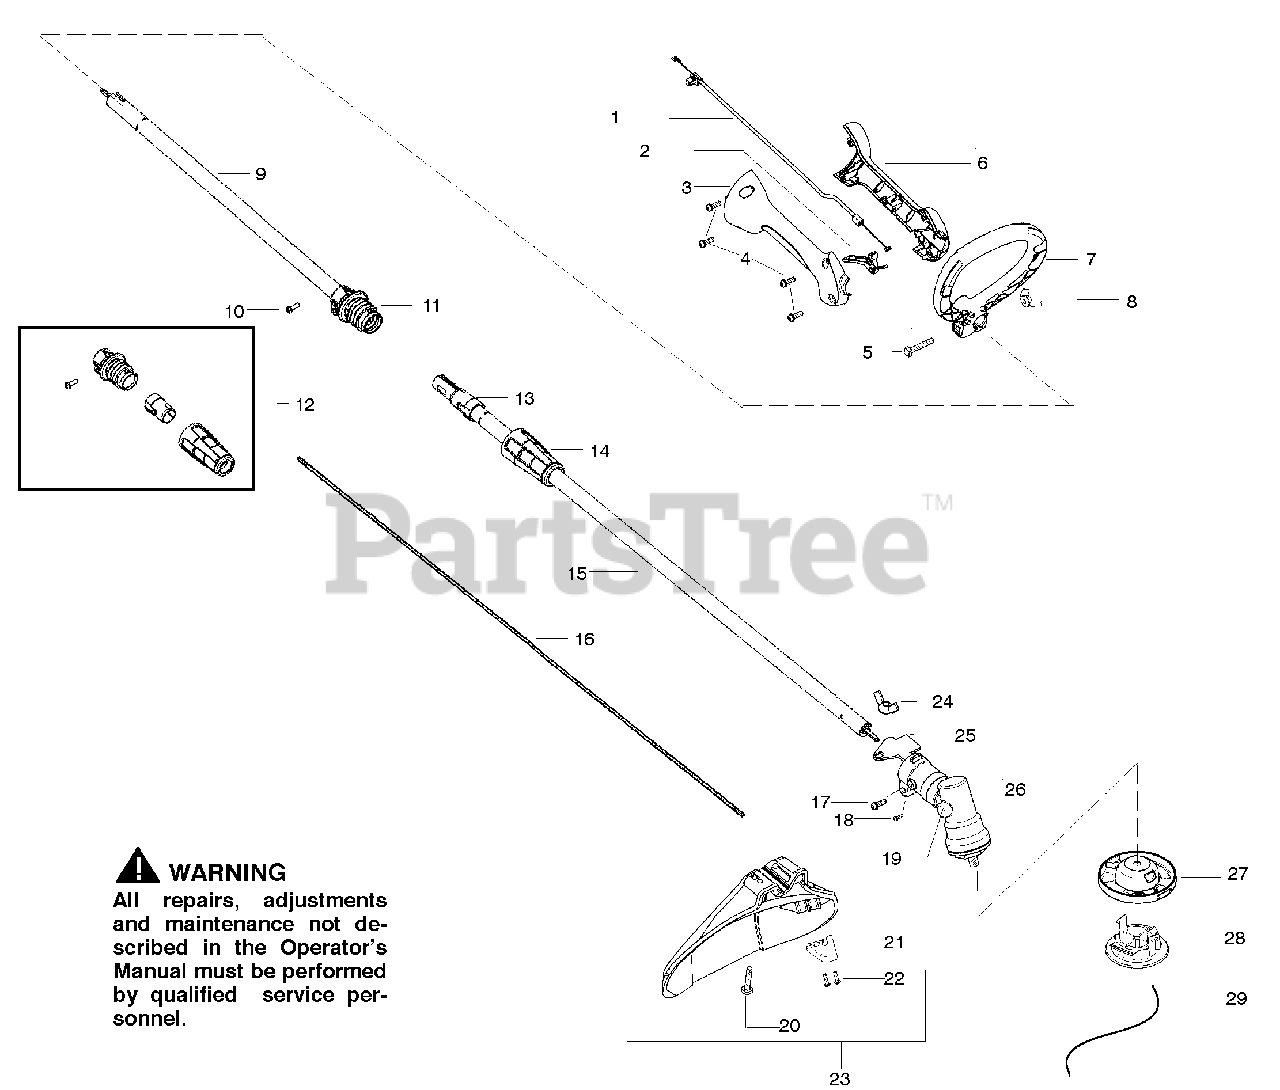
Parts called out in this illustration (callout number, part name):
1	ASSY THROTTLE CABLE
3	HSG THROTTLE RH
5	BOLT\-1/4-20X1-1/2
6	HSG THROTTLE LH
7	ASSY ASSIST HANDLE
8	WINGNUT, TYPE 2
9	KIT D'SHAFT UPPER BLK FLTCC
12	DRIVESHAFT KIT KD COUPLER
15	KIT D SHAFT LOWER 52"
16	ASSY FLEXSHAFT 51"
17	SCREW - CARB. ADAPTOR
19	PLUG GREASE 8MM
20	BOLT, TYPE 2
21	LINE LIMITER 17"
22	SCREW - THROTTLE HOUSING
23	KIT SHIELD
24	WINGNUT, TYPE 2
25	BRACKET SHIELD
26	GEARBOX ASSY 3/4
27	HEAD CUTTING FIXED LINE
28	CAP FIXED LINE 6
29	ACCY WE.095 X 16.5" LINE 12PCS
